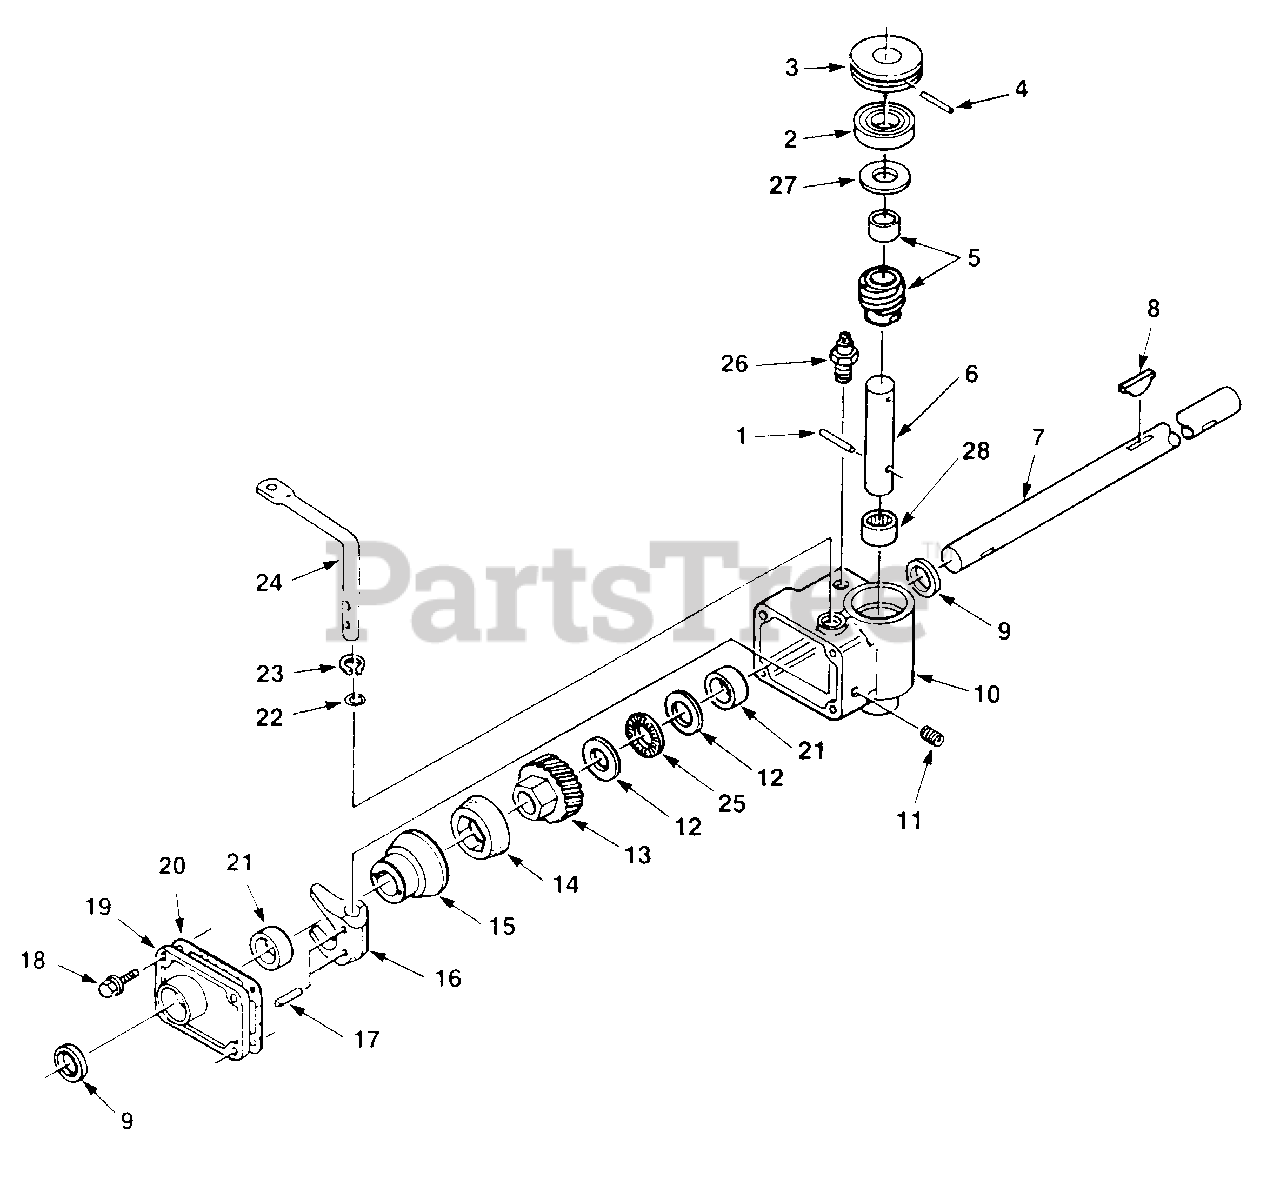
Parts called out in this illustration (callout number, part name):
1	PIN-Roll (3/16 x 7/8")
2	BEARING-Ball
3	PULLEY
4	PIN-Roll (3/32 x 1/4")
5	WORM & SPACER
6	SHAFT-Worm
7	SHAFT-Drive
8	KEY-(1/2 x 1/8")
10	GEAR REDUCER HOUSING ASSY.
11	PLUG-Pipe
12	RACE-Thrust
13	GEAR-Helical
14	CONE-Friction
15	DRUM-Clutch
16	FORK-Shift
17	PIN-Groove (5/32 x 3/4")
18	SCREW-Sems thd. (1/4-20 x 7/8")
19	COVER-Gearbox
20	GASKET
21	BUSHING-Sleeve
23	RING-Tru Arc Retaining
24	LEVER-Shift
25	BEARING-Thrust
28	BEARING-Needle
